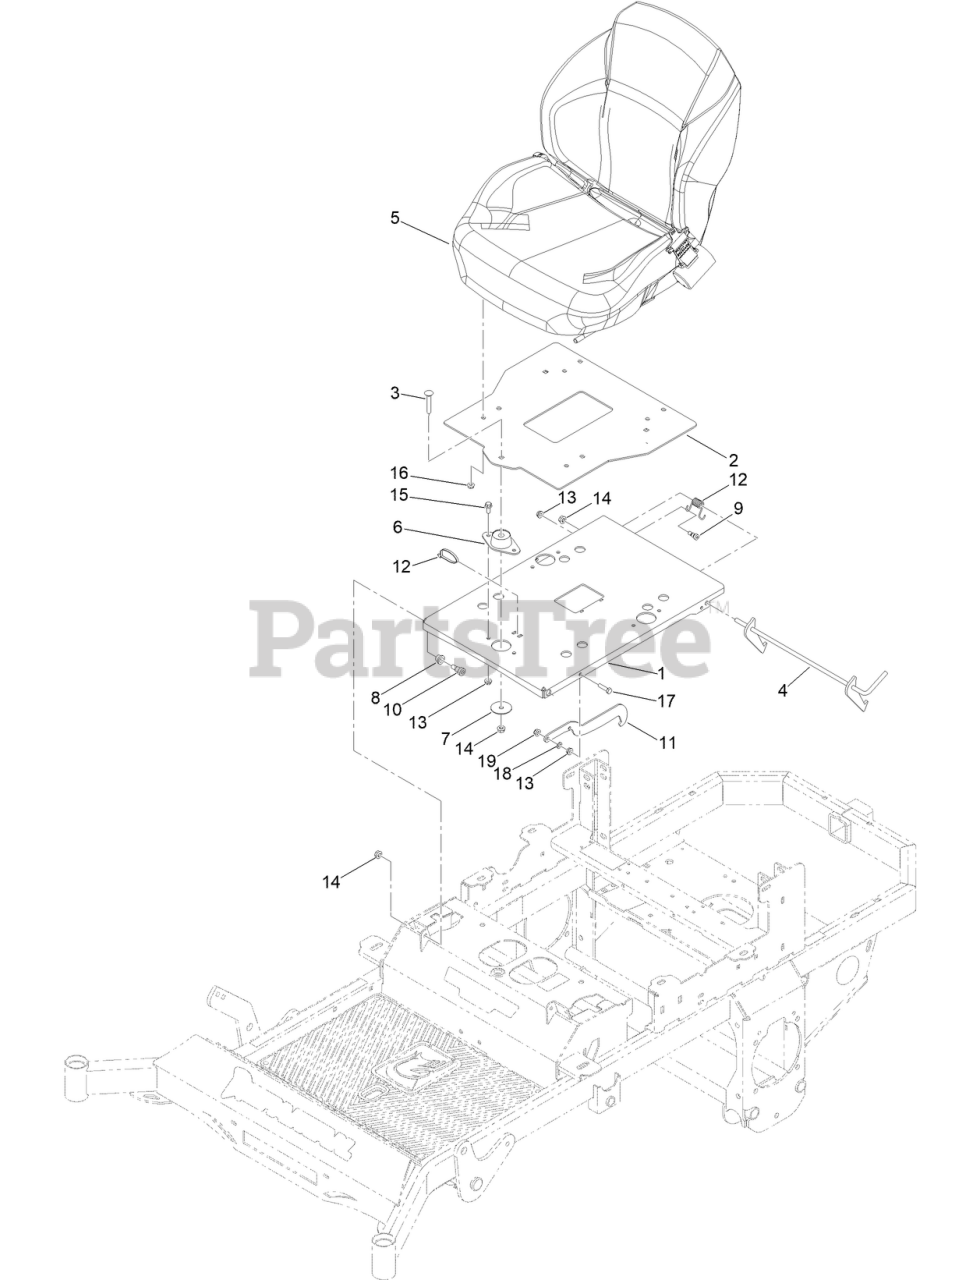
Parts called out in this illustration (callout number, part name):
1	ASM, PLATE-SEAT BASE UPGRADE W/ DECALS
2	2019 UPGRADE SEAT PLATE PAINT
3	SCREW-CARR
4	MWR SEAT LATCH RELEASE ASSY ABC
5	RT PRO SEAT
6	FLOATING SEAT DAMPER-STIFFER
7	3/8 X 2IN OD FENDER WASHER YZ
8	1/2IN ID X 5/8IN OD X 1/2IN FLANGE BUSH
9	SCREW-HSH
10	1/2 X 1/2 SOCKET SHOULDER BOLT ZC YELLOW
11	MWR SEAT LATCH HOOK PAINT
12	MWR SEAT LATCH SPRING
15	SCREW-HHF
16	5/16-18 NYLON INSERT FLANGE L/NUT ZC
17	SCREW-HH
18	.312IDX.625ODX.062 THK THRUST BRG OI BRZ
19	NUT-HF, NI
